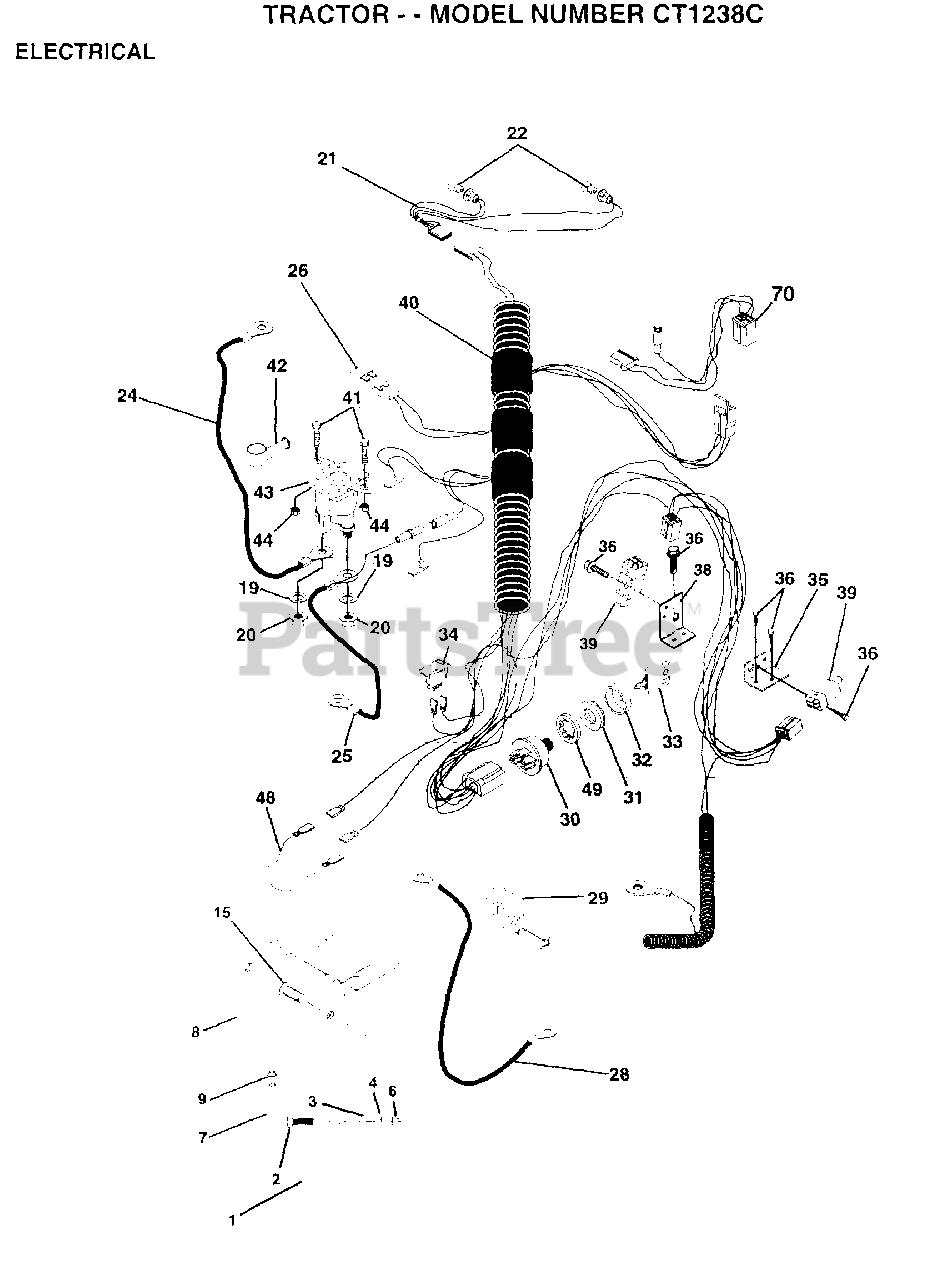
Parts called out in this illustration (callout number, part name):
2	BOLT LT
3	WASHER
4	LOCKWASHER
7	TUBE T
9	HOSE CLAMP T
15	FASTNER.SNAP-IN
20	NUT
21	"HARNESS,LIGHT SOC"
22	HEADLAMP BULB
24	"CABLE T, BATTERY"
25	CABLE.BTRY.6GA.RD
26	FUSE HYT
28	CABLE T
29	SWITCH SEAT
32	COVER KEY SWITCH
33	KEY MLD GEN DELTA
34	SWITCH LT
35	BRACKET LT
36	SCREW
38	BRACKET SWITCH IN
39	SWITCH INTERLOCKT
40	HARNESS.IGN.DASH.
41	BOLT HXHD FIN
44	NUT HXKEP 1/4X20
48	ADAPTER AMMETER
49	LOCKWASHER
70	HARNESS ENG DUAL
